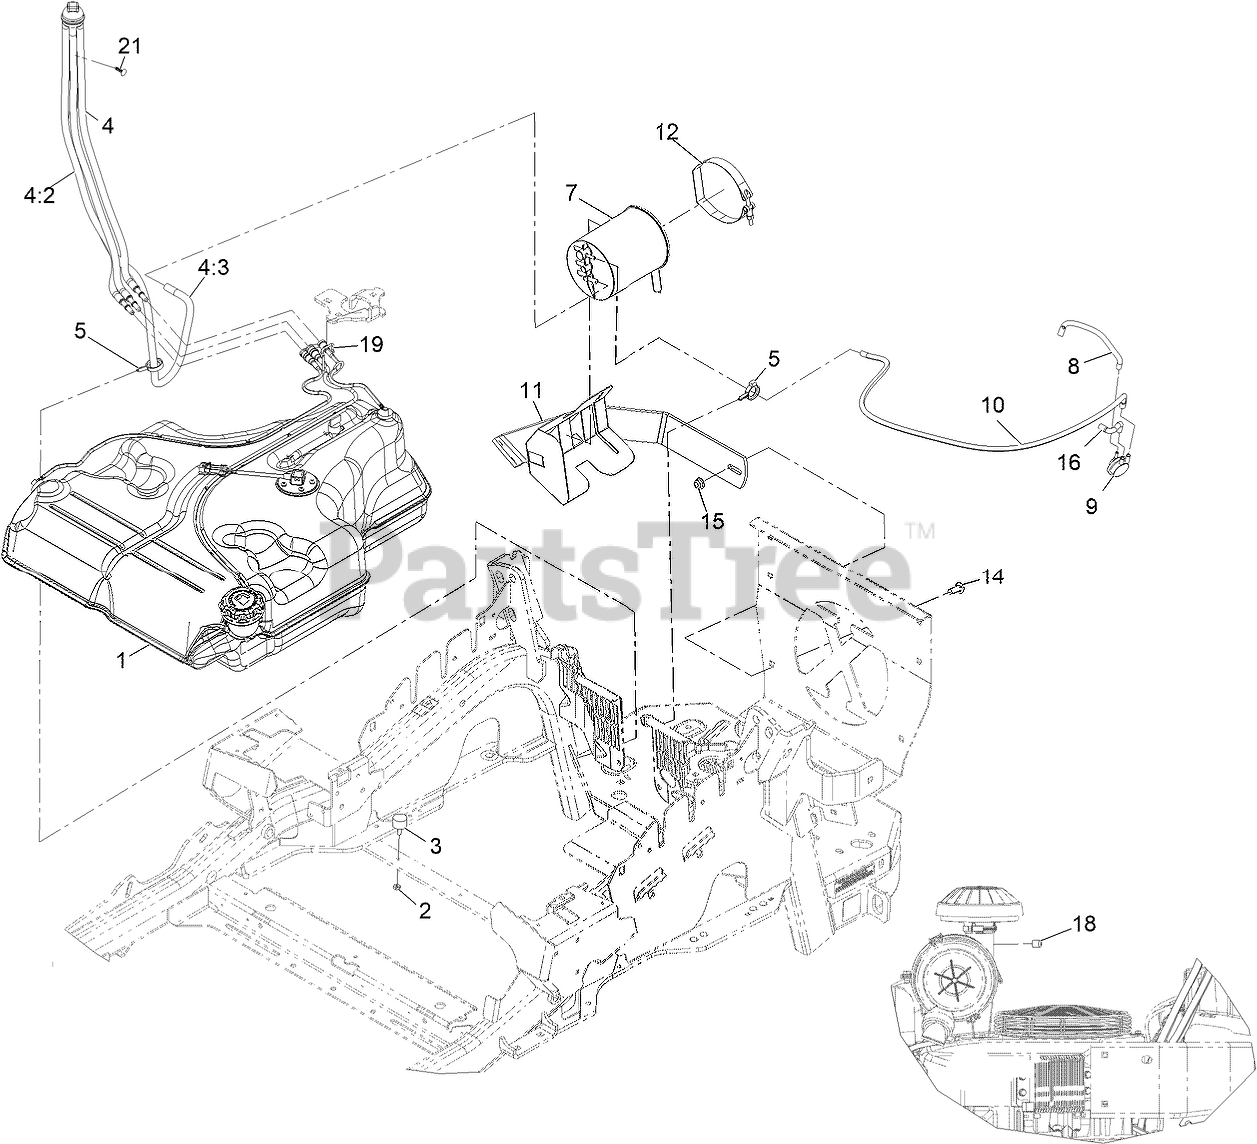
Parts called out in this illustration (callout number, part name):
1	FUEL TANK ASM
2	NUT-JAM
4	FUEL MANIFOLD VENT ASM
4:2	HOSE-FUEL
4:3	HOSE-FUEL
5	CLAMP-HOSE
7	CANISTER-CARBON, 1200CC
8	HOSE-VENT,FORMED
9	VALVE-CONTROL, VACUUM
10	HOSE,VENT,FORMED
11	MOUNT-CANISTER
12	CLAMP, T-BOLT
14	SCREW-CARR
15	NUT-HF, NI
16	HOSE-VENT, FORMED
18	PLUG-PORT
19	RETAINER-LINE, VAPOR
21	PLUG-PLASTIC
